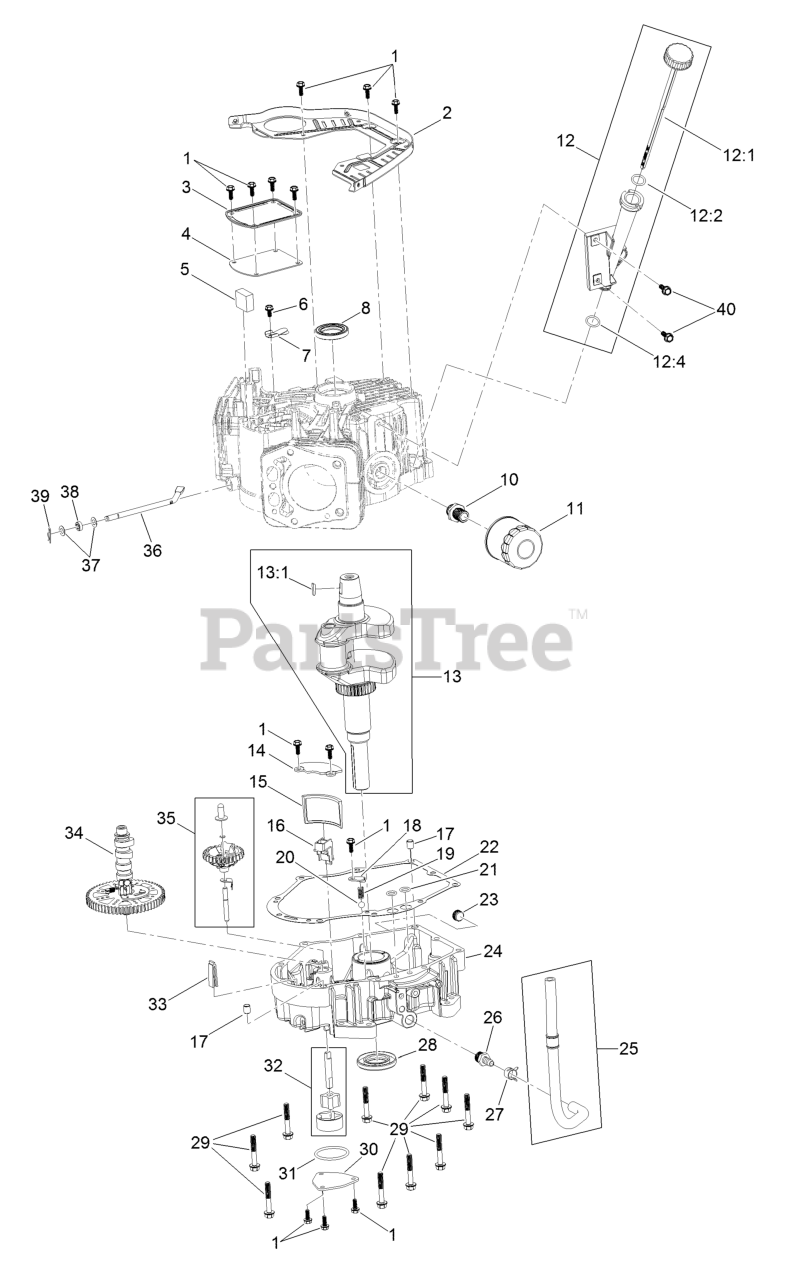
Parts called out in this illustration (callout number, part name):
1	Screw-HHF
3	Cover-Breather
4	Gasket-Breather
5	Filter-Breather
6	Screw-HHF
7	Valve-Breather
8	Seal-Oil
10	Adaptor-Filter, Oil
11	Filter-Oil
12	Oil Tube ASM
12:1	Dipstick
13	Crankshaft
13:1	Key-Woodruff
14	Cover-Screen, Oil
15	Screen-Oil
16	Retainer-Screen
17	Pin-Dowel
18	Plate-Retainer
20	Valve-Ball
22	Gasket-Cover, Crankcase
23	Plug-Drain
24	Cover-Crankcase
25	Oil Drain Hose ASM
26	Fitting-Hose
27	Clamp-Hose
29	Screw-HHF
30	Cover-Oil Pump
32	Oil Pump ASM
33	Deflector-Oil, Rubber
34	Camshaft
35	Governor ASM
36	Rod-Governor
37	Washer-Plain
38	Seal-Oil
39	Pin-Hair
40	Screw-HHF
